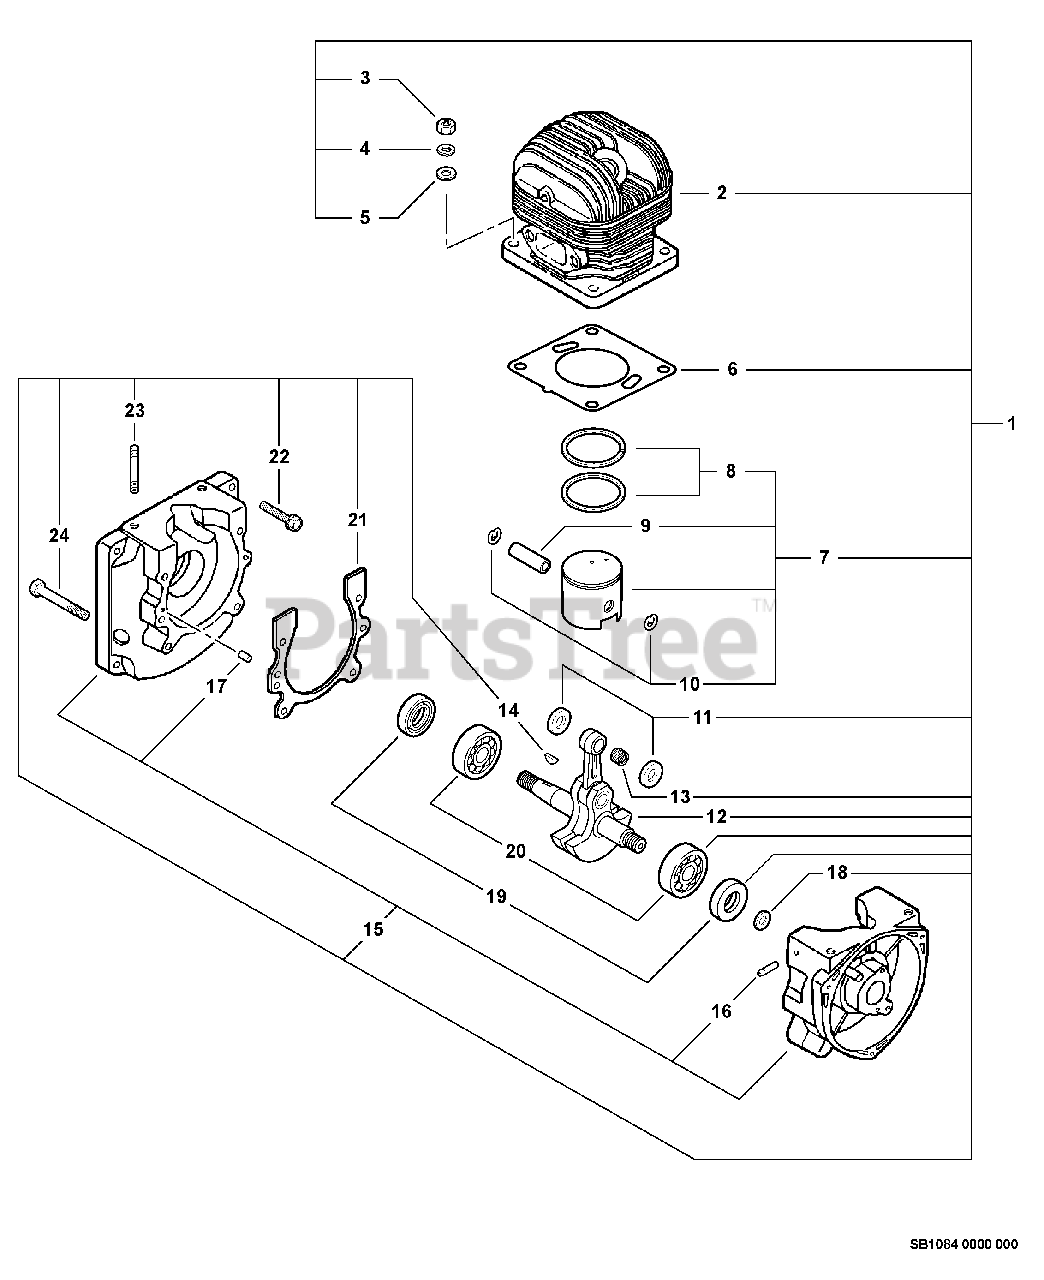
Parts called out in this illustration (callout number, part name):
1	SHORT BLOCK
2	CYLINDER
3	NUT, HEX M6
4	WASHER, SPRING 6
5	WASHER 6.5×11.5×0.8
6	GASKET, CYLINDER
7	PISTON KIT
8	RING, PISTON
9	PIN, PISTON
10	RING, SNAP 8
11	WASHER, THRUST
12	CRANKSHAFT ASSY
13	BEARING, NEEDLE 10
15	CRANKCASE KIT
16	CONNECTOR
17	PIN, LOCATING 5×10
18	WASHER PB-400
19	SEAL, OIL
20	BEARING, BALL 6202
21	GASKET
